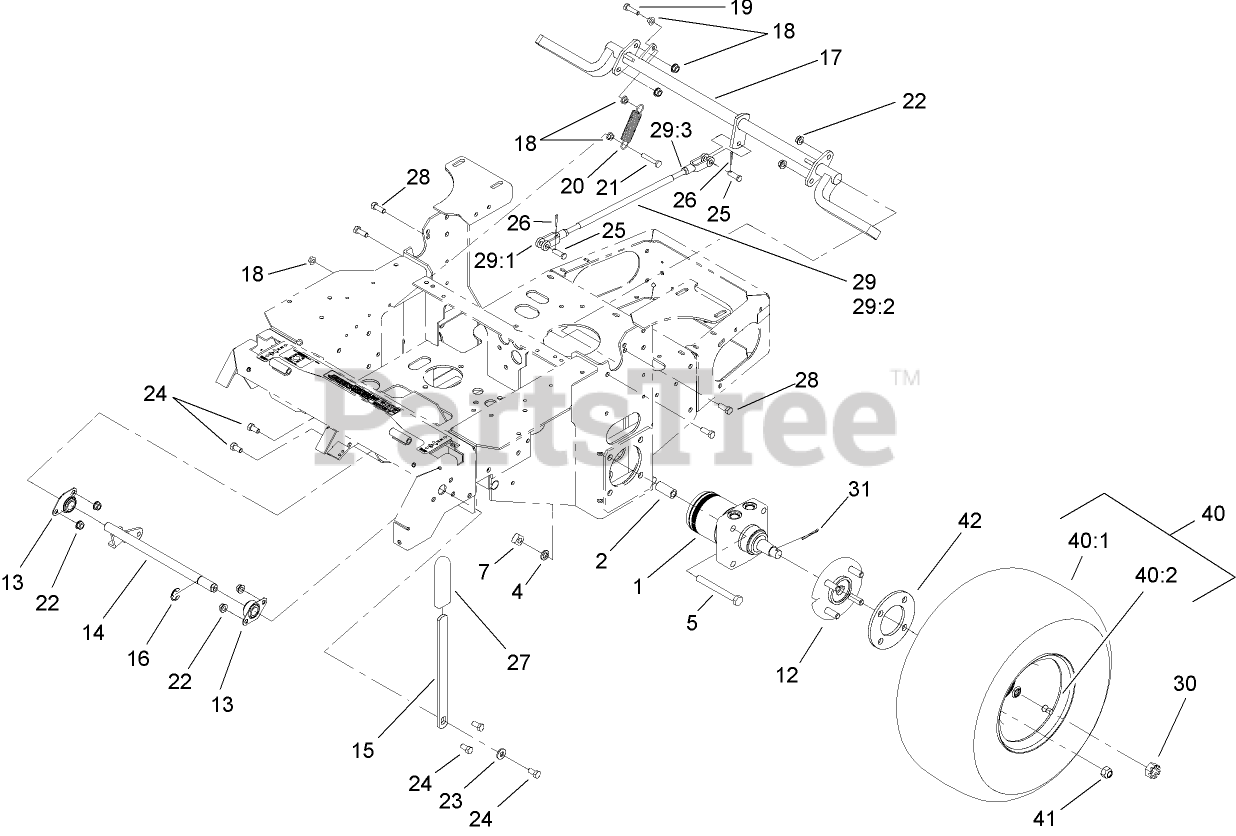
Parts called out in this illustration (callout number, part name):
1	MOTOR-WHEEL
2	SPACER-MOTOR, WHEEL
4	WASHER-LOCK
5	SCREW-HH
7	NUT-SQUARE
12	HUB ASM W/STUDS
13	BEARING-FLANGE, SIDE
14	Shaft-Brake, Parking
15	HANDLE-BRAKE, PARKING
16	E-RING
18	NUT-HF
19	SCREW-HH
20	SPRING-IDLER
21	SCREW-HH
22	NUT-HHF, WHIZ
23	WASHER-BELLEVILLE
24	SCREW-HH
25	PIN-CLEVIS
26	PIN-COTTER
27	GRIP-LEVER
28	SCREW-HH
29	BRAKE ROD ASM
29:1	YOKE-LINKAGE, BRAKE
29:2	LINKAGE-HANDLE, BRAKE
29:3	NUT-HEX
30	NUT-HEX, SLOTTED
31	PIN-COTTER
40	WHEEL AND TIRE ASM
40:1	TIRE
41	NUT-LUG
42	SPACER-WHEEL
